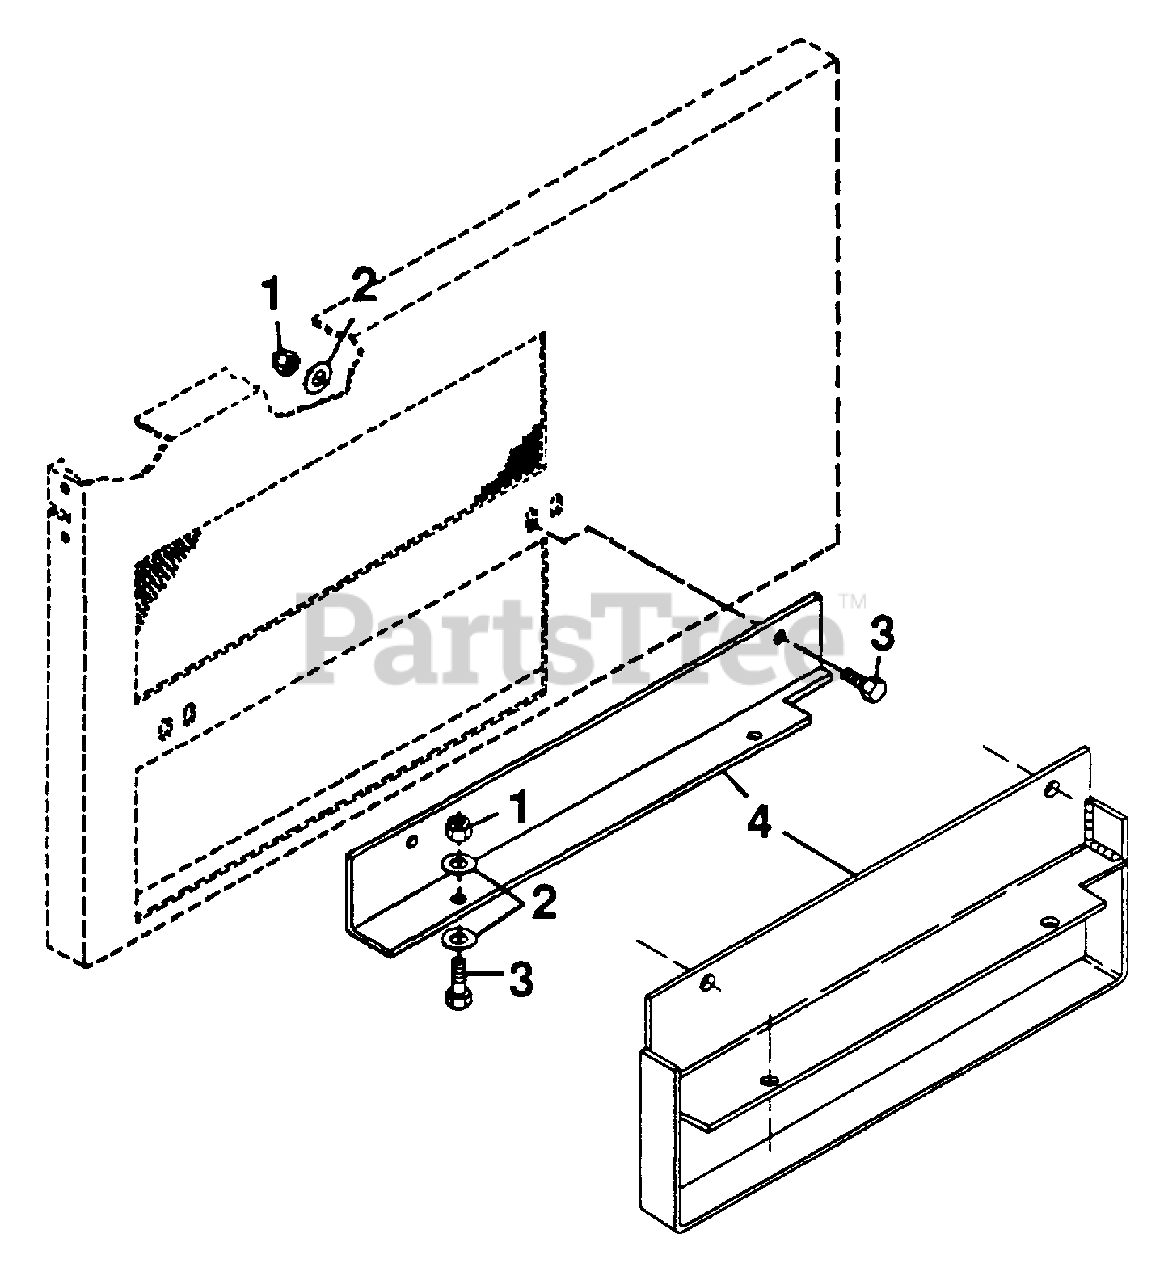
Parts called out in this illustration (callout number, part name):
1	BOLT, HEX 3/8-16X1.00
2	WASHER, FLAT .406X.812X.065
3	NUT, LOCK 3/8-16
4	ADAPTER, PRO 36
4	ADAPTER, 32" MOWER
